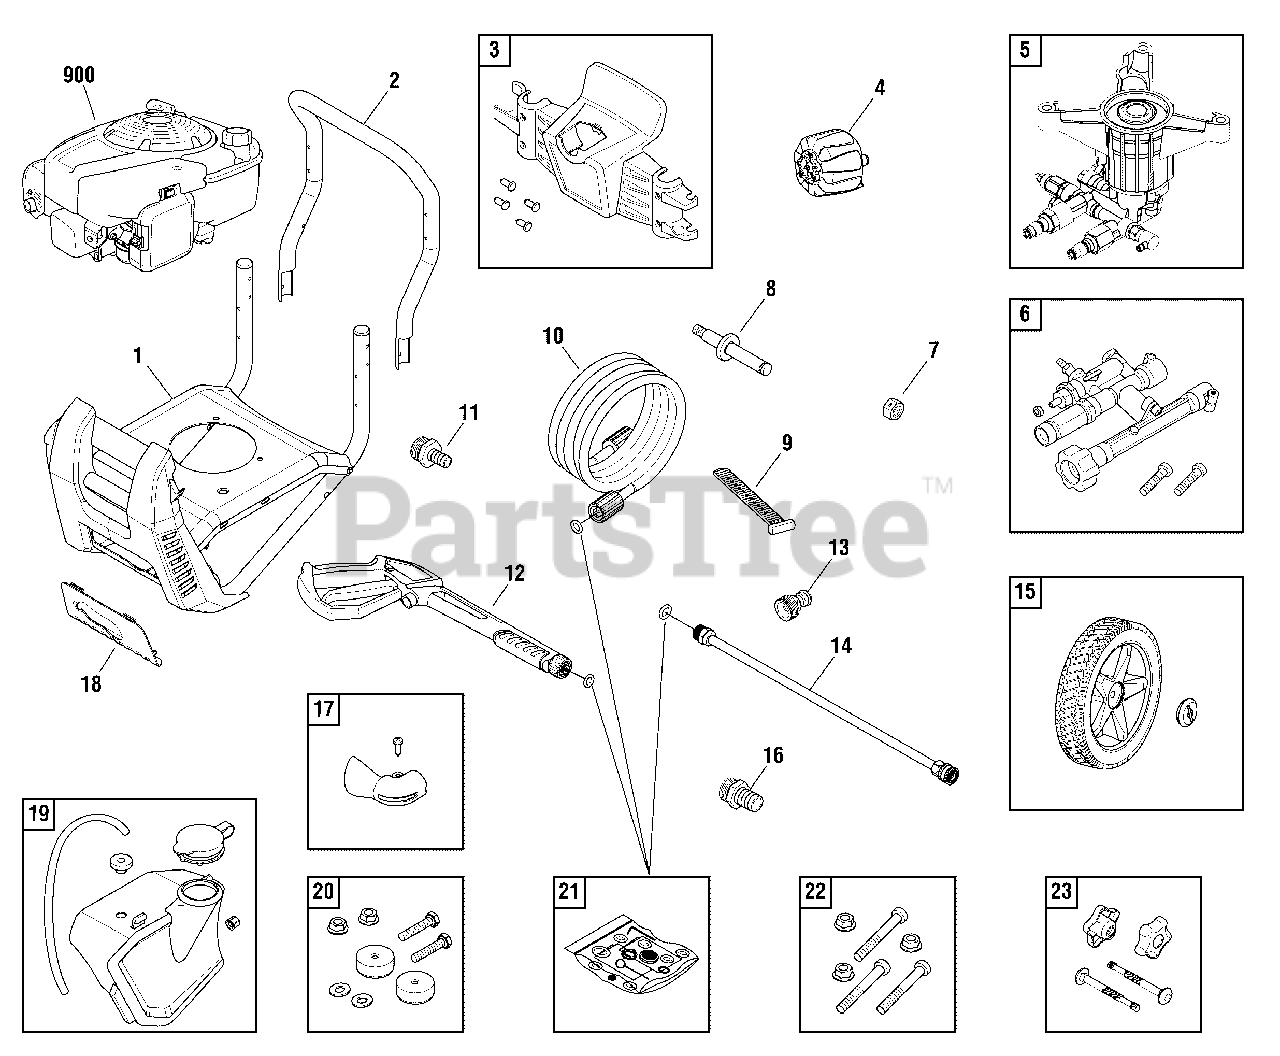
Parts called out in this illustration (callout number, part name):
6	POWERFLOW
10	HOSE
12	GUN
13	QUICK CONNECT
17	DEFLECTOR-EXHAUST
19	TANK-CHEMICAL
20	MOUNT-VIBRATION
22	KIT-HARDWARE PUMP MOUNTING
23	KIT-HARDWARE HANDLE
900	* ENGINE
